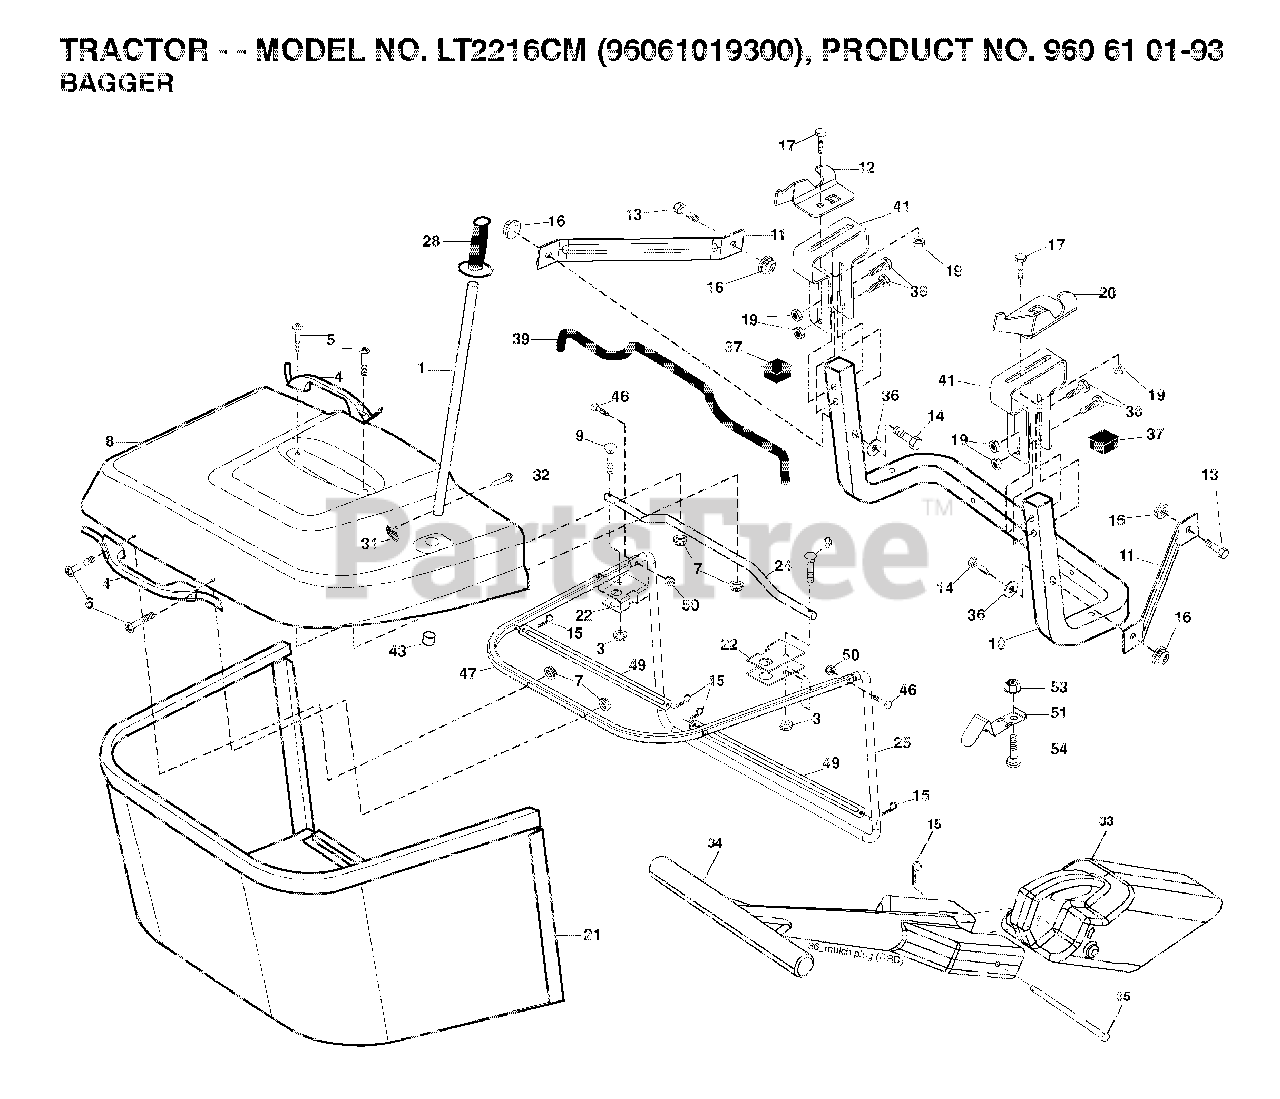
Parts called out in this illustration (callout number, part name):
1	TUBE HANDLE
3	NUT T
5	SCREW.PAN.HEAD
11	BRACKET
14	BOLT-HEX EAK
15	RETAINER-SPRNG RB
16	NUT LOCK FLG 3/8-16 UNC
17	BOLT
19	NUT LOCK HEX FLANGE 5/16-18
20	BRKT.PIVOT.RH.CRD
21	BAGGER.ASM.CRD.2007
22	BRACKET
24	TUBE
28	GRIP.HANDLE.BLACK
31	RETAINER CLIP
32	RIVET,DRILLED
33	PLUG
35	PIN
38	BOLT.5/16-18X2.5
41	BRKT, BAGGER
43	PLUG, TUBING END
46	BOLT.CARRIAGE.5/16-18
50	NUT.71038.31-18.HEX.NYLOCK
53	NUT
54	BOLT
